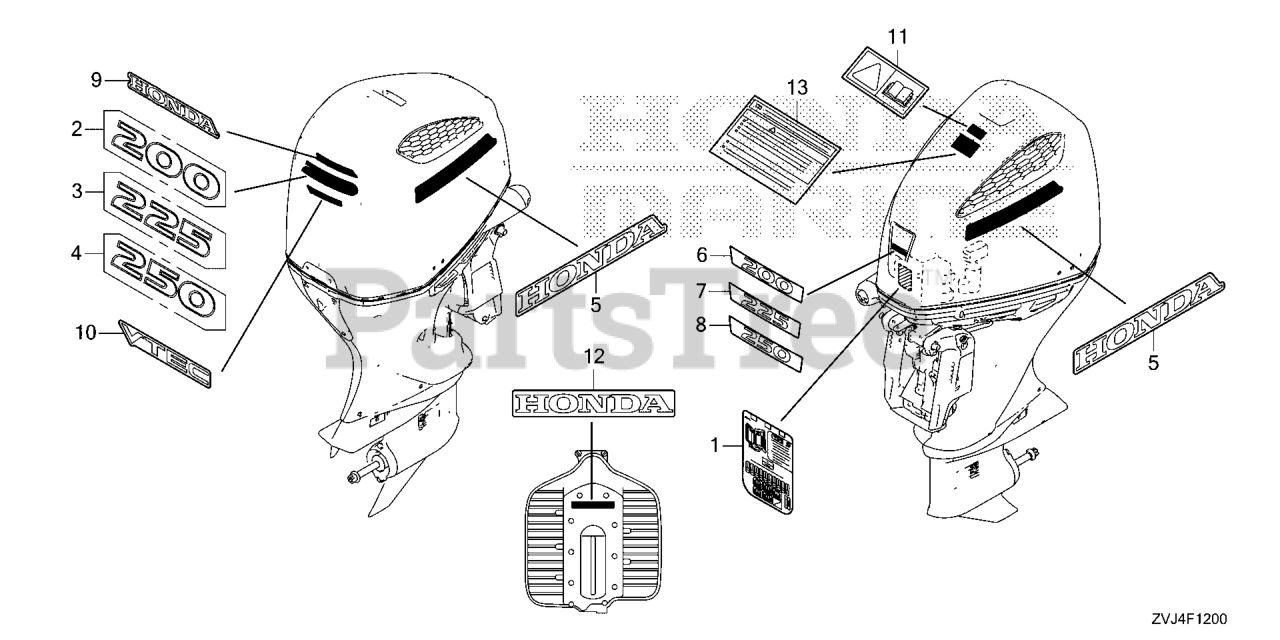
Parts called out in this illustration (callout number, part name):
4	MARK, RR. (BF250)
5	MARK, SIDE STRIPE (BF250)
8	MARK, FR. EMBLEM (BF250)
9	MARK, HONDA
10	MARK (VTEC)
12	EMBLEM (13) (HONDA)
13	LABEL, WARNING OPERATOR (ENGLISH)
